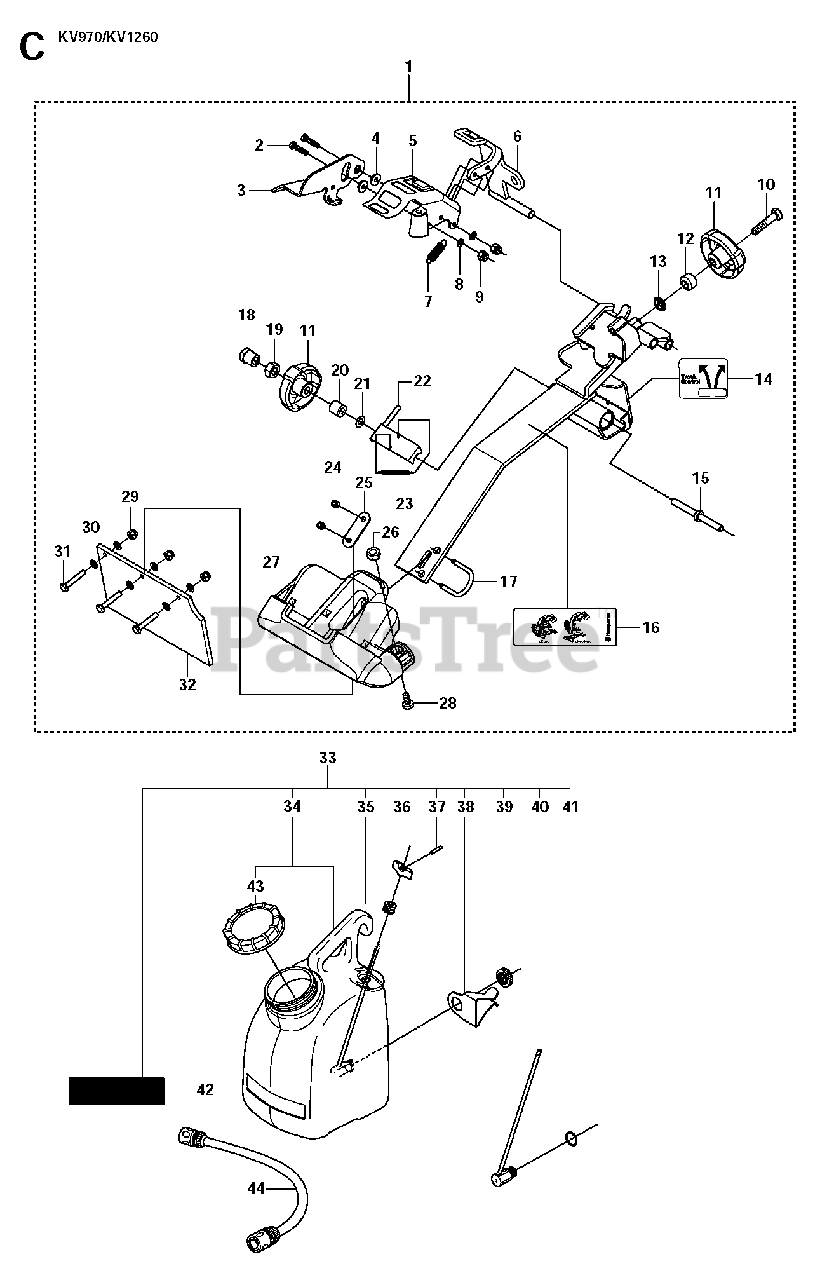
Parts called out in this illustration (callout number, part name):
1	HOLDER ASSYIncl. 2 - 32
8	WASHER
9	HEXAGON LOCKING NUT
11	TURNING KNOB
19	HEXAGON NUT
20	SPACING SLEEVE
24	HEXAGON LOCKING NUT
26	HEXAGON NUT
29	HEXAGON LOCKING NUT
33	WATER TANKIncl. 34 - 42
35	ANTIVIBRATION ELEMENT
